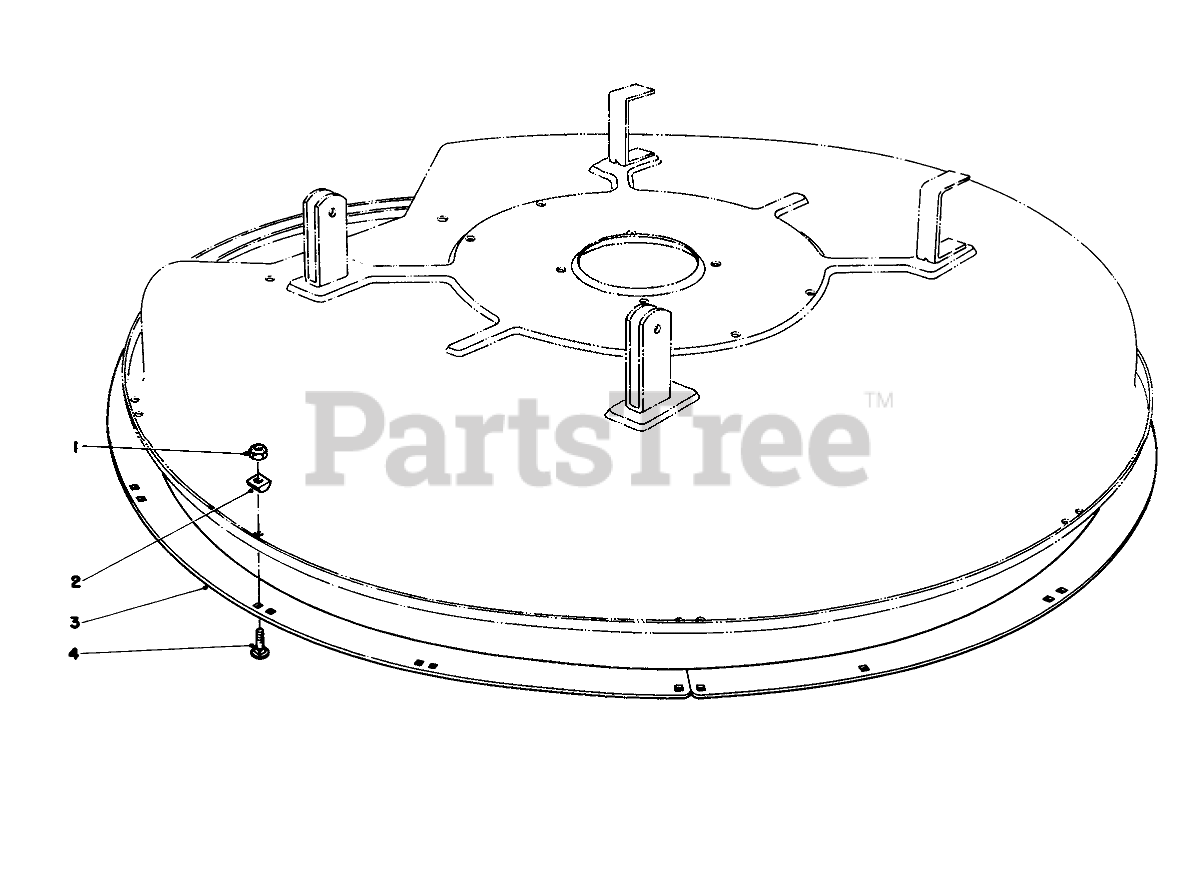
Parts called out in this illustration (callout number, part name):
1	NUT-LOCK, NI
2	DECK RING SPACER
3	DECK RING B
4	BOLT-CARR
